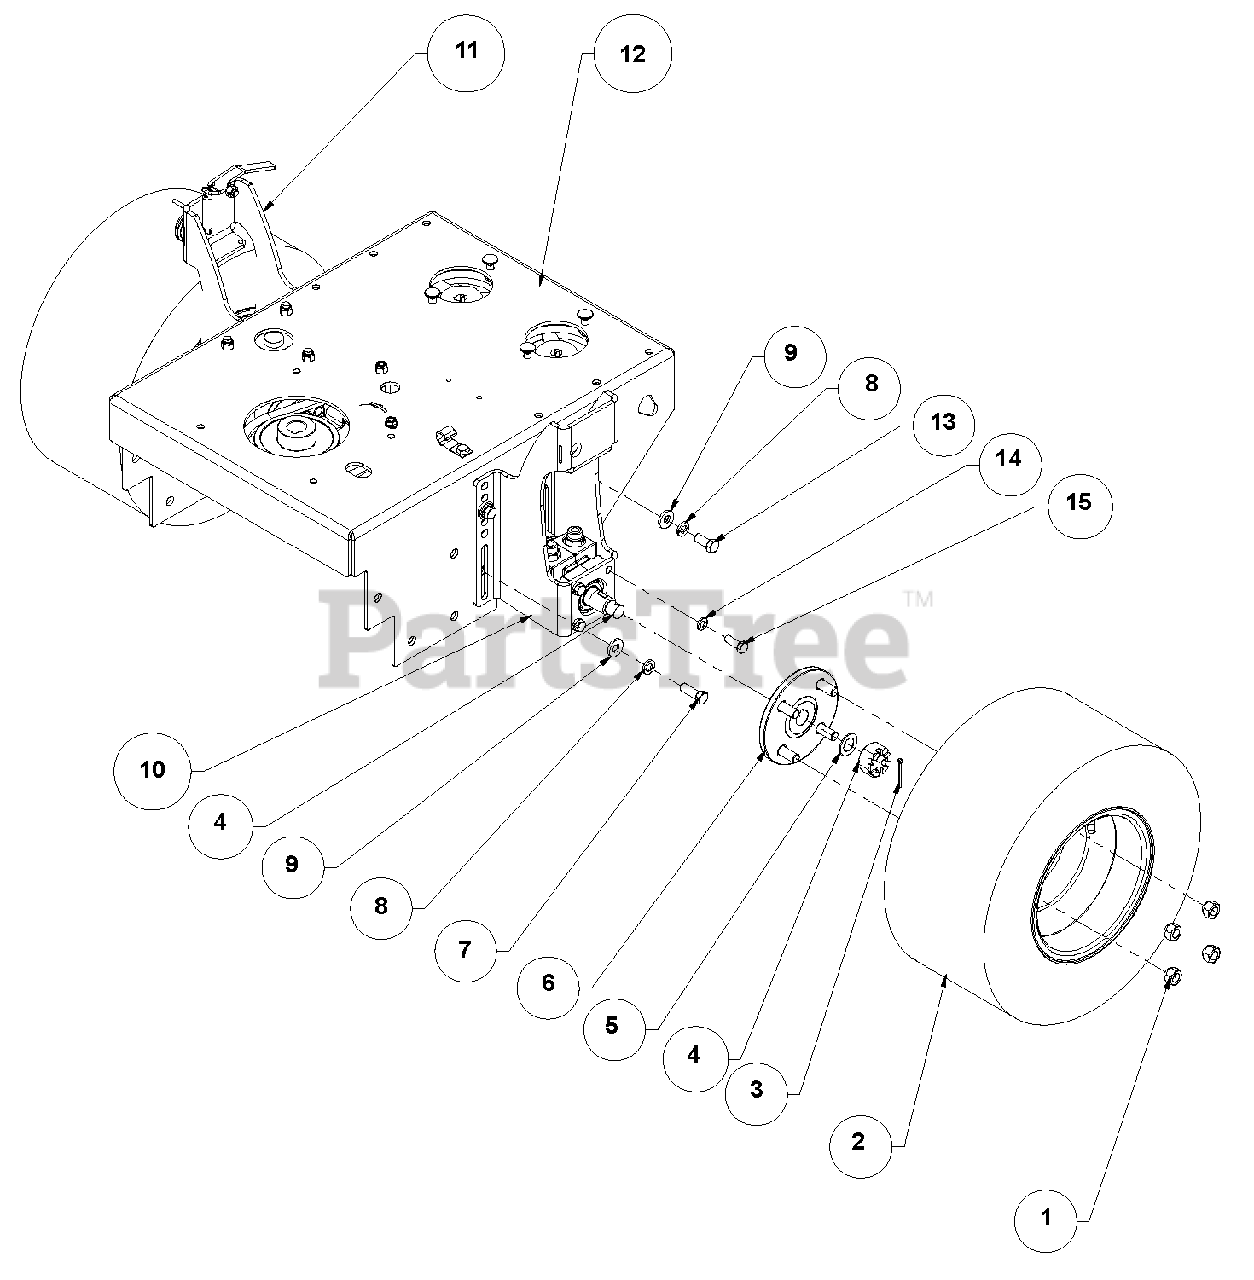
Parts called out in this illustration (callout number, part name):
1	Nut, .50-20 Lug
2	Assembly, Wheel and Tire- 16 x 6.5-8
3	Pin, Cotter .125 x 1.50 EXTP
4	Motor, Hydraulic Wheel
5	Bushing, Machine .750 x 1.25 x .048
6	Assembly, Wheel Hub
7	Bolt, .4375-14 x 1.25 Hex 5
8	Washer, .438 Medium Spring Lock
9	Washer, .468 x 1.00 x .125 Flat
10	Bracket, Left Hand Combo WD EverRide (402)
11	Bracket, Right Hand Combo WDEverRide (402)
12	Weldment, Engine Plate TDF EverRide
13	Bolt, .4375-14 x 1.00 Hex 5
14	Washer, .375 Medium Spring Lock
15	Bolt, .38-16 x 1 Grade 8 Black
